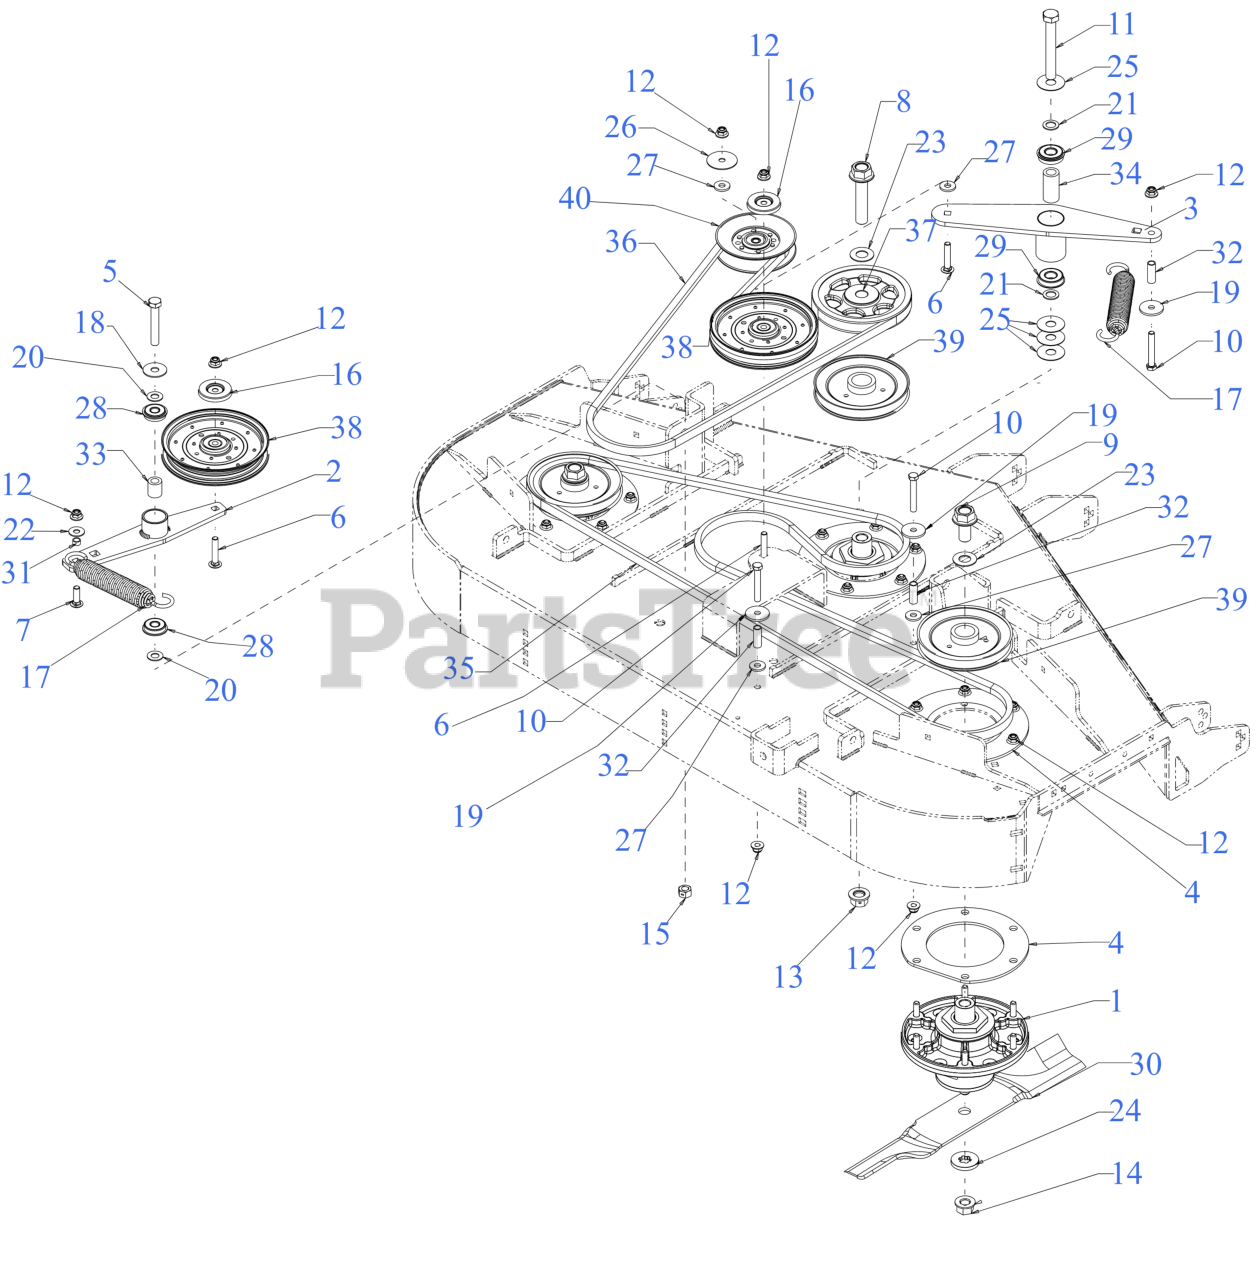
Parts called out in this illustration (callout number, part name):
1	SPINDLE ASSEMBLY
2	IDLER BRACKET
3	IDLER BRACKET
4	SPINDLE SUPPORT BRACKET TOP/BTM
5	SCREW-HEX 1/2-13 x 3.00
6	CARRIAGE BOLT 3/8-16 x 2
7	CARRIAGE BOLT 3/8-16 X1.25 GR5
8	CAP SCREW-HHFLG 3/4-10 X 3.50 GR8
9	CAP SCREW-HHFLG 3/4-10 X 1.50 GR8
10	HEX SCREW-3/8-16X2.5 GR5
11	SCREW 5/8-18X4.5 GR5
12	NUT
14	FLANGE NUT - 5/8-18 GDE 8
15	HEX NUT CTR LK 1/2-13
16	PULLEY CAP
17	SPRING 1.25" DIA x 8.5" LONG
18	WASHER .51 x 1.5 x .07
19	FLAT WASHER .390x1.500x.134
20	FLAT WASHER .510 x .995
21	FLAT WASHER
22	WASHER-.395 x 1.0 x .62
23	FLAT WASHER
24	FLAT WASHER - SPECIAL
25	THRUST WASHER .635x1.750x0.055
26	HUB CAP WASHER .406 x 1.92 x .060
27	FLAT WASHER .406ID X1.0 OD
28	ROLLER BEARING .5X1.37X.44
29	BALL BEARING W/RET
30	19" BLADE (HI LIFT)
30	Cub Cadet 54" HI LIFT BLADE SET
30	LOW-LIFT 19"BLADE (54"DECK)
30	BLADE- HI LIFT 19.0 XTREME
30	BLADE-19"MULCH 54"
30	19" XTREME BLADE
33	SPACER 0.51 x 0.88 x 1.00
34	SPACER 0.63 x 1.00 x 2.01
35	BELT-B SECTION 119.45"
36	BELT SEC B x 90.30
37	PULLEY 6.96 OD x .750 ID
38	IDLER PULLEY
39	SPINDLE PULLEY 6"
40	IDLER PULLEY 5.06 OD
